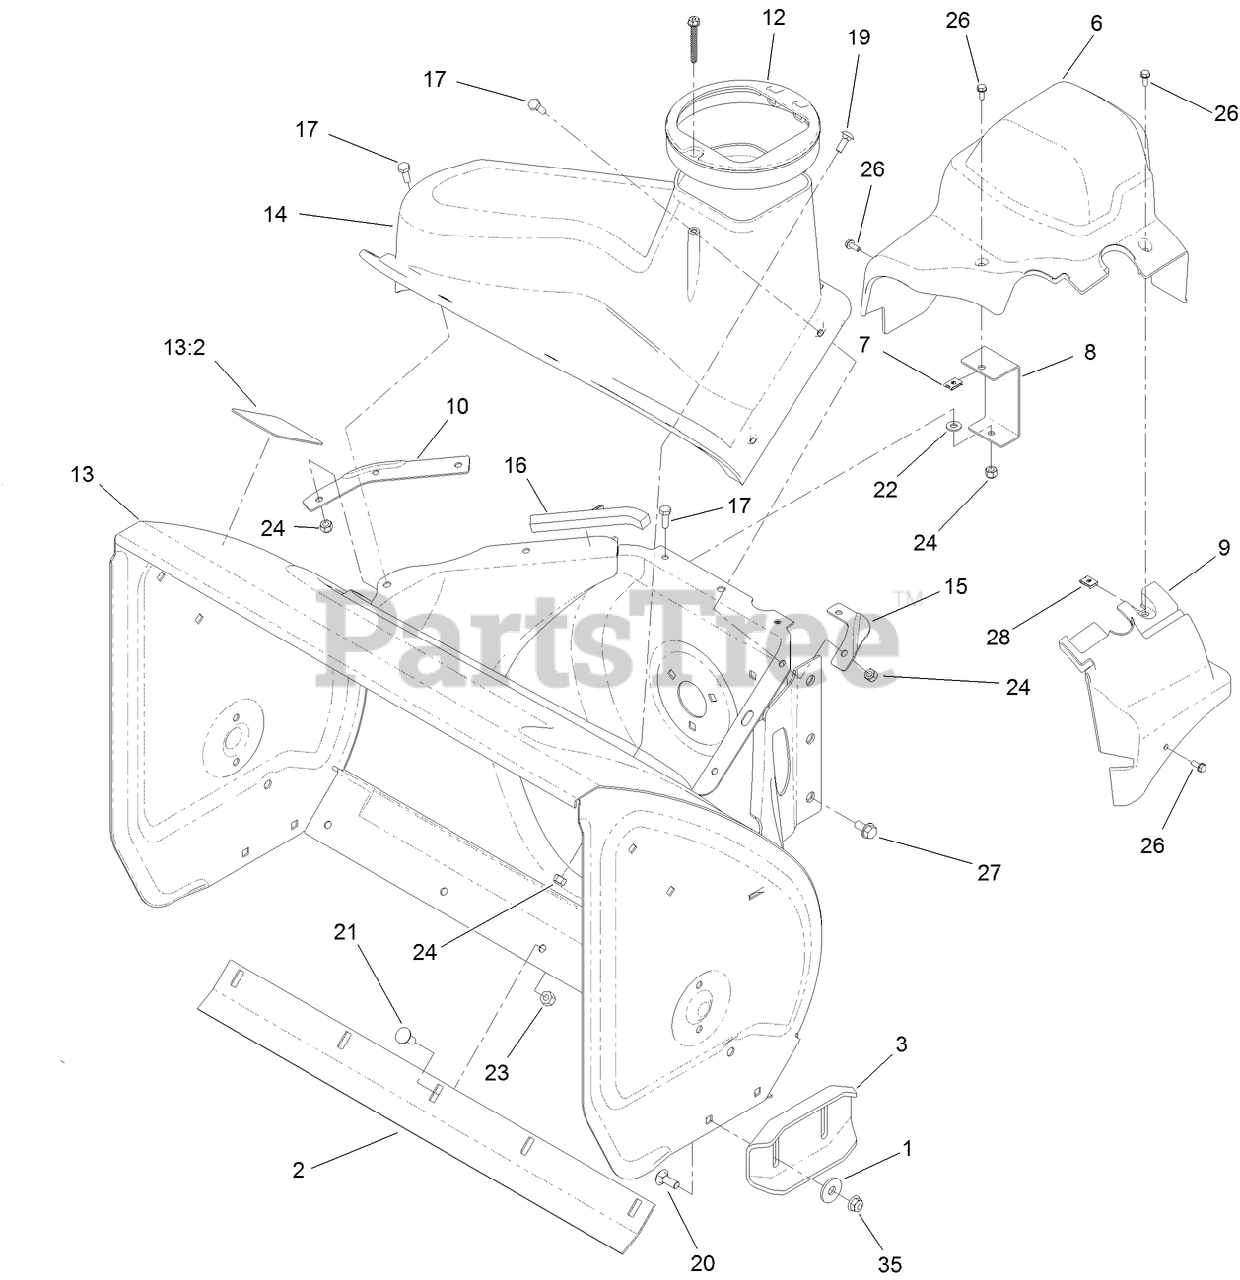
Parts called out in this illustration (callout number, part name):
1	WASHER-FLAT
2	SCRAPER-FIXED
6	COVER-BELT
7	NUT-SPEED
8	BRACKET-COVER, CLIP NUT
9	COVER-EXTENSION, BELT
10	SEAL-FLANGE, COVER
12	GUIDE-CHUTE
13	HOUSING-AUGER, 26 INCH
13:2	DECAL-DANGER
16	SEAL-HOUSING
17	SCREW-HH
19	BOLT-CARR
20	BOLT-CARR
21	BOLT-CARR
22	WASHER-FLAT
23	NUT-HEX
24	NUT-HEX
26	SCREW-HWH
27	SCREW-HWHTF
28	NUT-SPEED
35	NUT-HF
